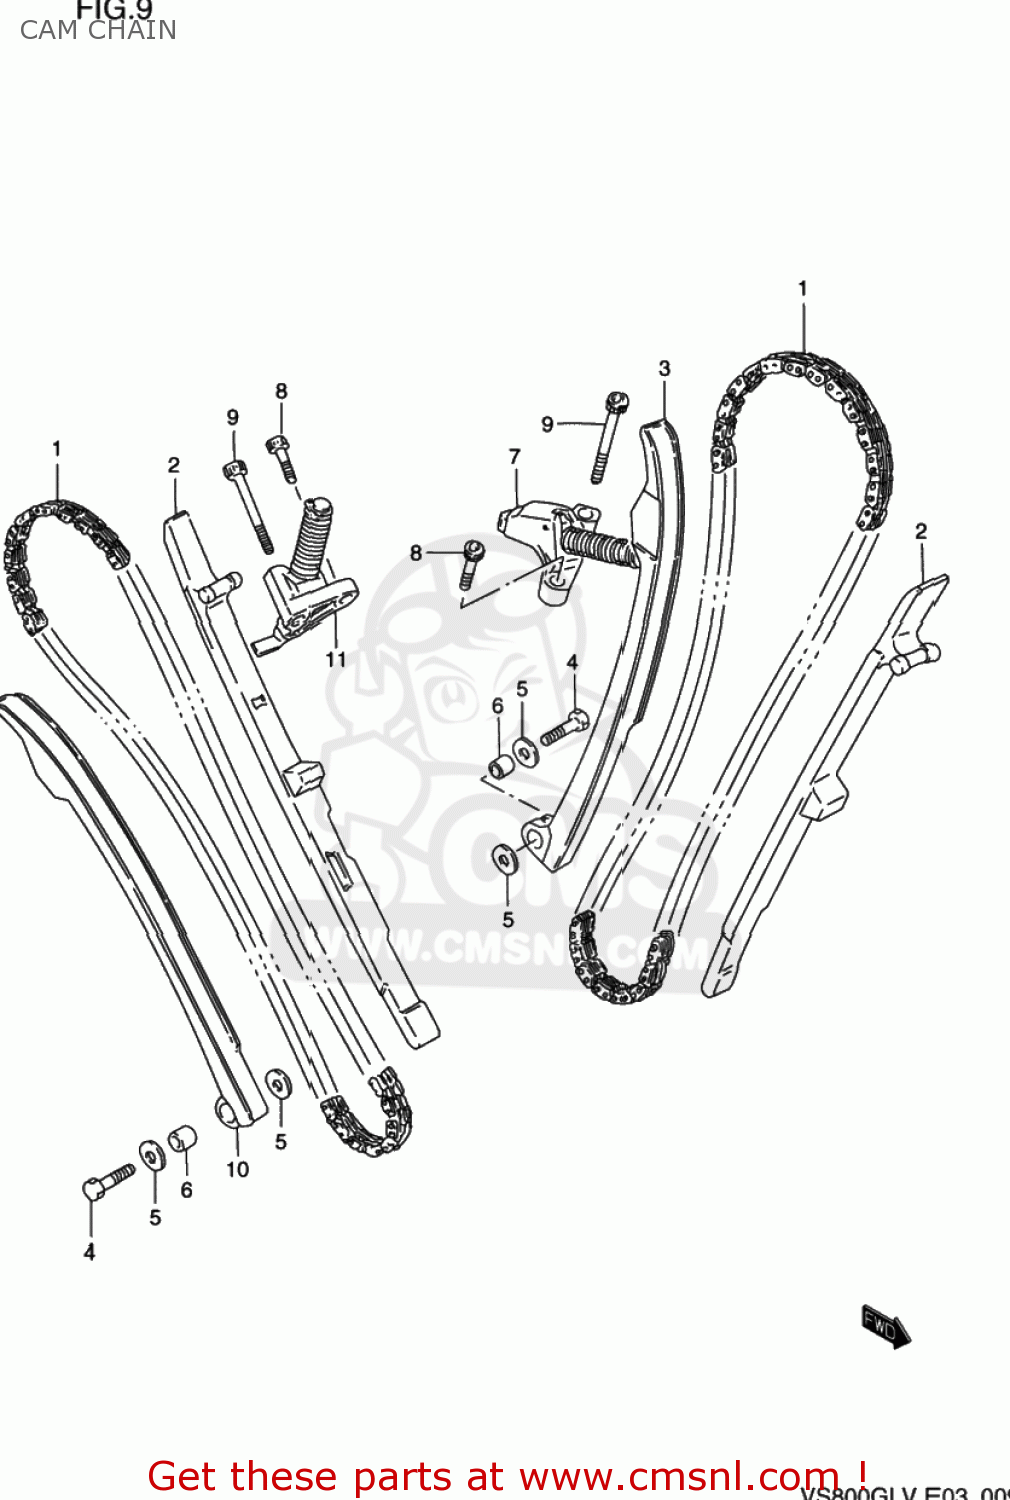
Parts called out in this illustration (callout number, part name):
1	CHAIN,CAMSHAFT DRIVE
2	GUIDE,CAM CHAIN
3	TENSIONER,FR CAM CHAIN
4	BOLT(6X26)
5	WASHER
6	SPACER(6X11X11)
7	ADJUSTER ASSEMBLY,FRONT TENSIONER
8	BOLT
9	BOLT
10	TENSIONER,RR CAM CHAIN
11	ADJUSTER ASSEMBLY,REAR TENSIONER
